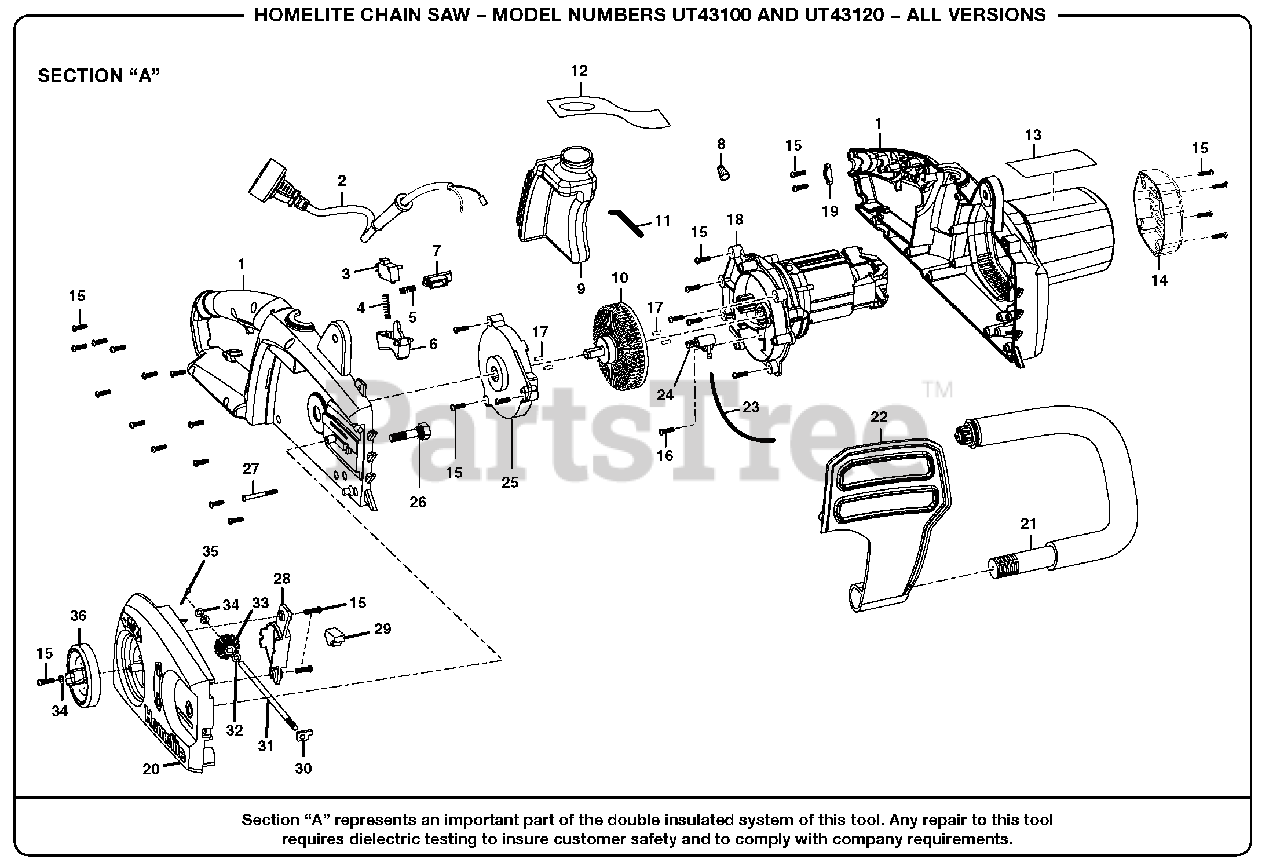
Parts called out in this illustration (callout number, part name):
1	Housing Assembly
2	Power Cord
4	Trigger Spring
5	Lock-off Spring
7	Lock-off Button
9	Oil Reservoir Assembly
10	Ring Gear Assembly
11	Oil Tube, Inlet
12	Hang Tang
13	Data Label
14	Motor Cap
15	Screw (M4 x 14 mm)
16	Screw (M3.8 x 14 mm)
17	Rubber Pin
18	Motor Assembly
19	Cord Clamp
20	Chain Cover
21	Front Handle
23	Oil Tube, Outlet
25	Ring Gear Cover
26	Chain Bar Stud
27	Screw (M4.2 x 45 mm)
28	Gear Cover
29	Rubber Pad
30	Adjustment Pin
31	Shaft
33	Adjustment Gear
35	Cotter Pin
36	Adjustment Knob
